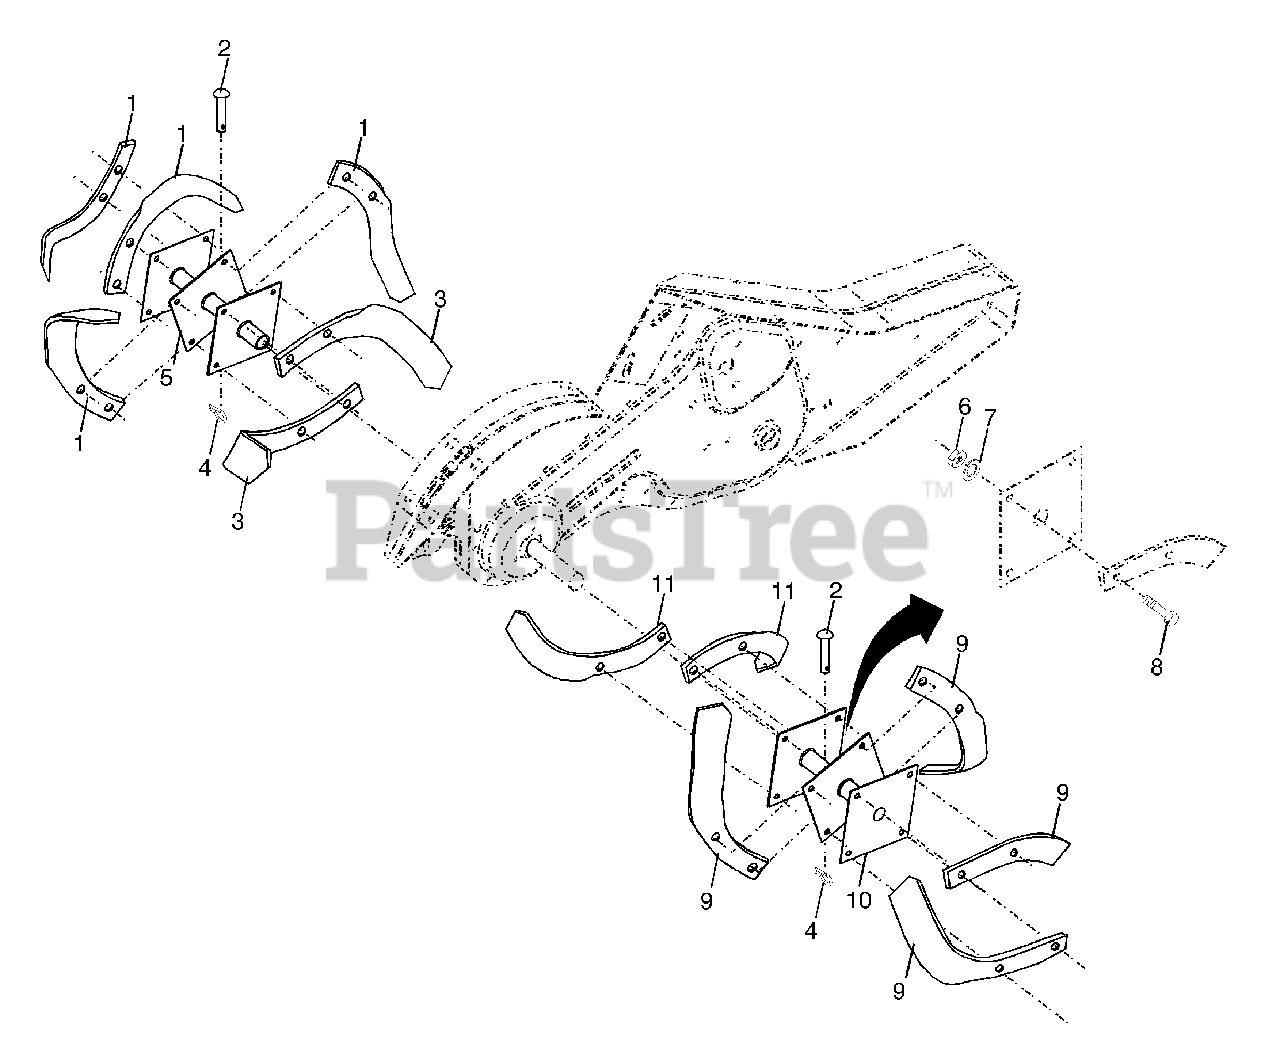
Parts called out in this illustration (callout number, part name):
1	Tine, Outer, L.H.
2	Clevis Pin
3	Tine, Inner, L.H.
4	Retainer, Spring
5	Assembly, Hub and Plate, L.H.
6	Nut, Hex 3/8-24
7	Washer, Lock 3/8
8	Bolt, Hex 3/8-24 x 1
9	Tine, Outer, R.H.
10	Assembly, Hub and Plate, R.H.
11	Tine, Inner, R.H.
